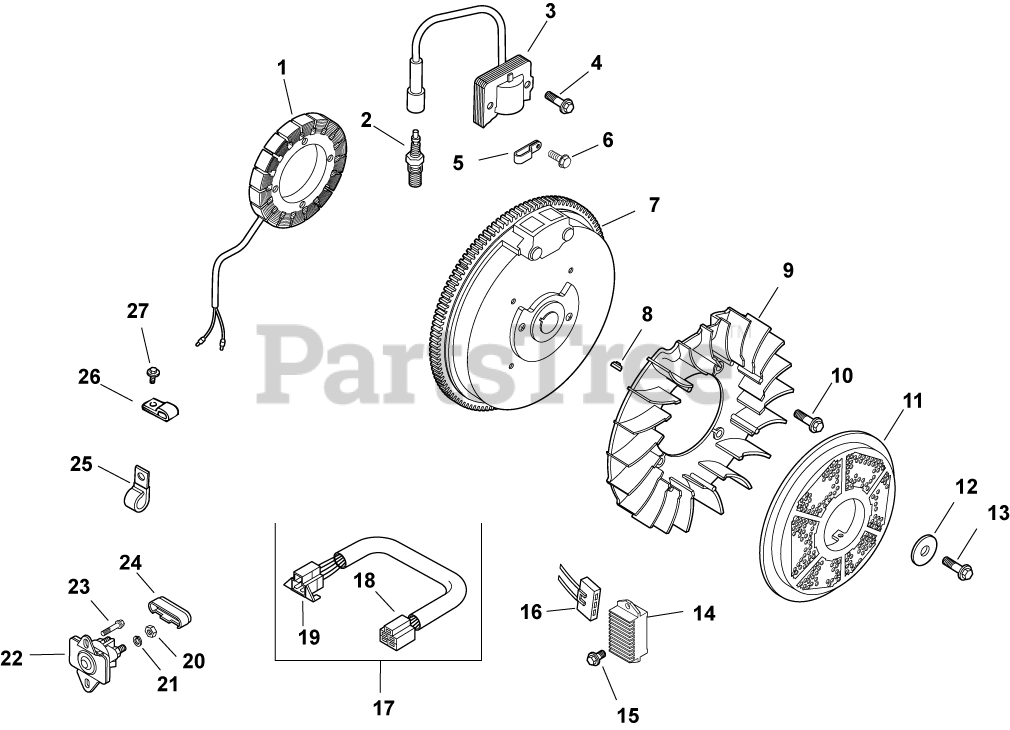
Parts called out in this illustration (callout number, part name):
1	KIT, 15 / 20 AMP STATOR
2	PLUG, SPARK (STD)
3	MODULE, IGNITION
4	SCREW, FLG THD FRM M5X.8X20-(#25086399S)
6	SCREW, FLG THD FRM M5X.8X10
8	KEY, 3/16" X 5/8"
9	FAN - DISCONTINUED
10	BOLT, SHOULDER
11	SCREEN, GRASS
12	WASHER, FLAT 13/32"
13	SCREW, FLG M10X1.5X45 - (#25086361S)
14	REG/RECT-15 AMP (KM)-USE 41 403 10-S
15	SCREW, FLG M6X1.0X16
16	CONNECTOR, BODY (KM)-USE 25 155 41-S
17	CONNECTOR ASSEMBLY
18	CONNECTOR
19	CONNECTOR
20	NUT, JAM 1/4-20 GRADE 2
21	WASHER, INT TOOTH LOCK 1/4"
22	SOLENOID - WATERPROOF (KM)-USE 25 435 08
23	SCREW,FLG THD FRM M6X1.0X16-(#25086397S)
24	CAP, SOLENOID - DISCONTINUED
25	CLIP, CABLE
26	CLIP, TUBE & WIRING (KM)
27	SCREW, M5X0.8X25 - (#25086402S)
